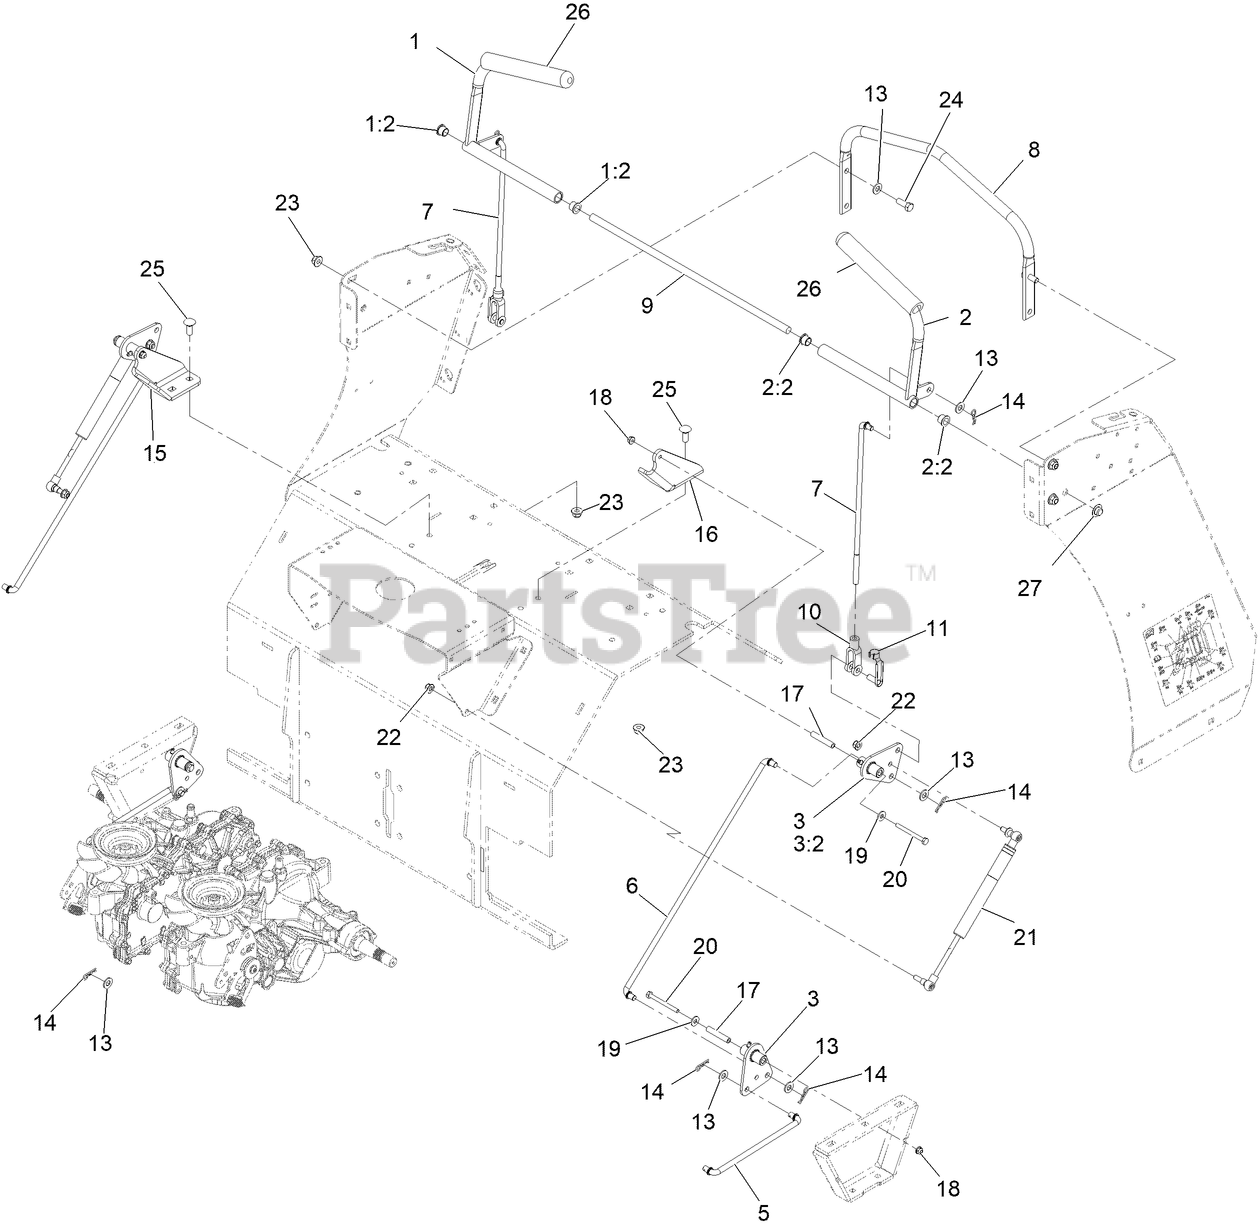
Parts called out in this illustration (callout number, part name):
1	RH CONTROL HANDLE ASM
1:2	BEARING-FLANGE
2	LH CONTROL HANDLE ASM
2:2	BEARING-FLANGE
3	CRANK-BELL
3:2	FITTING-GREASE
5	LINK-CONTROL, HYDRO
6	LINK-CONTROL, BELL CRANK
7	LINK-CONTROL, BELL CRANK
8	BAR-REFERENCE
9	SHAFT-PIVOT, CONTROL
10	YOKE-LINKAGE, BRAKE
11	PIN-SPRING, CLEVIS
13	WASHER-FLAT
14	PIN-COTTER
15	BRACKET-PIVOT, RH
16	BRACKET-PIVOT, LH
19	WASHER-FLAT
20	SCREW-HH
21	DAMPER, MOTION CONTROL
22	NUT-HF, NI
23	NUT-HF, NI
24	SCREW-HH
25	BOLT-CARR
26	GRIP-LEVER, CONTROL
27	NUT-PUSH
